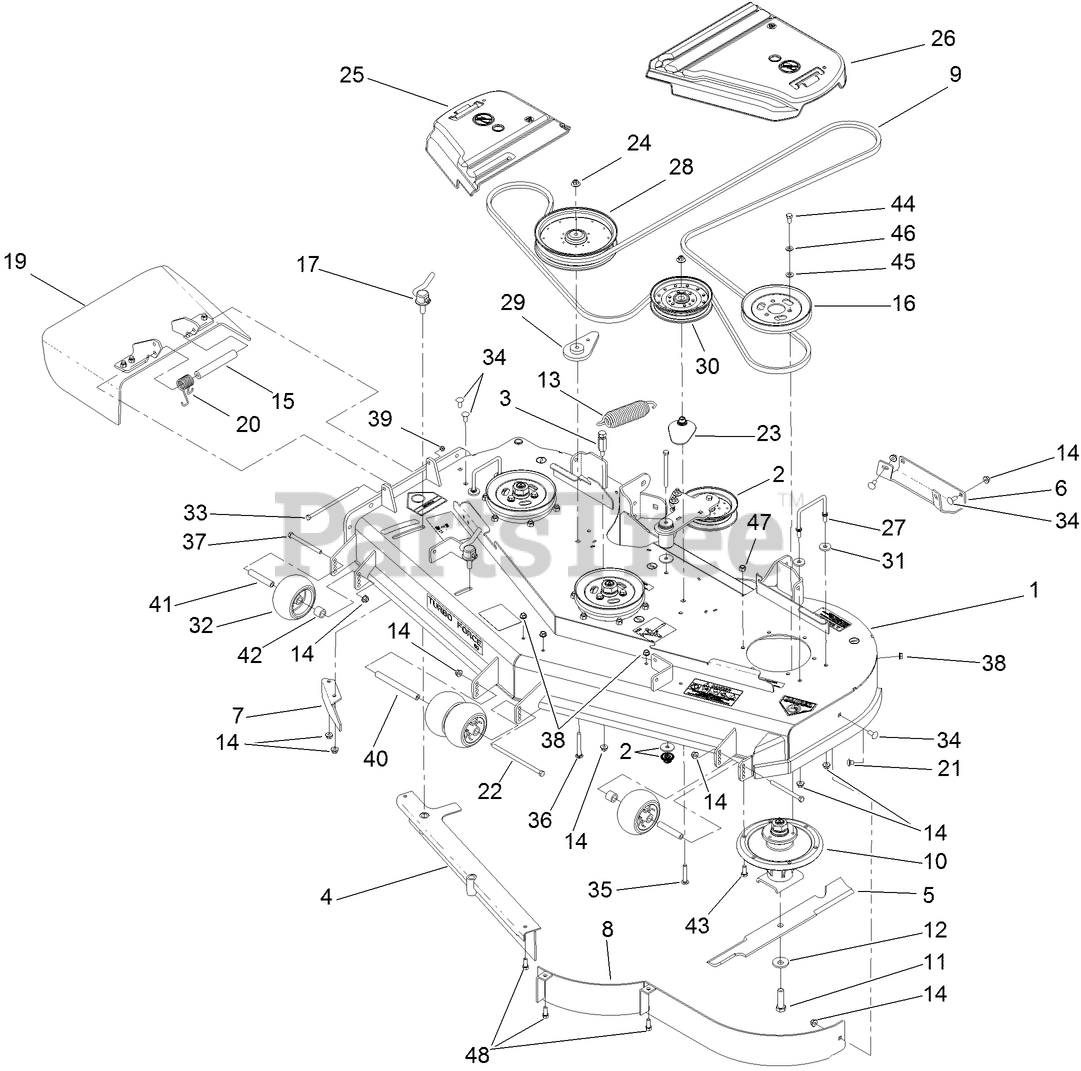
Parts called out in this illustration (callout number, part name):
1	DECK DECAL ASM
2	IDLER ARM ASM
3	ANCHOR-SPRING, TALL
5	BLADE-HI FLOW
6	PLATE-SKID
7	BAFFLE-DISCHARGE
9	BELT-V
10	SPINDLE ASM
11	SCREW-BLADE
12	WASHER-BLADE BOLT, HEAVY
14	NUT-HF, NI
15	SPACER
16	PULLEY
17	LEVER ASM
19	RUBBER DEFLECTOR ASM
20	SPRING-TORSION
21	SCREW-CARR
22	SCREW-HH
23	SPACER-PULLEY
24	NUT-FLANGE, NI
25	COVER-BELT, RH
26	COVER-BELT, LH
27	WIREFORM-COVER
28	PULLEY-IDLER
29	SPACER-IDLER
31	WASHER
32	ROLLER-SCALP, ANTI
33	SCREW-HH
34	SCREW-CARR
35	BOLT-CARR, SHORT NECK
36	SCREW-CARR
37	SCREW-HH
38	NUT-HHF, WHIZ
39	NUT-LOCK, NI
40	SPACER-WHEEL
41	TUBE-SPANNER
42	TUBE-SPACER
43	SCREW-HH
44	SCREW-HH
45	WASHER-FLAT
46	WASHER-BELLEVILLE
47	NUT-LOCK, NI
